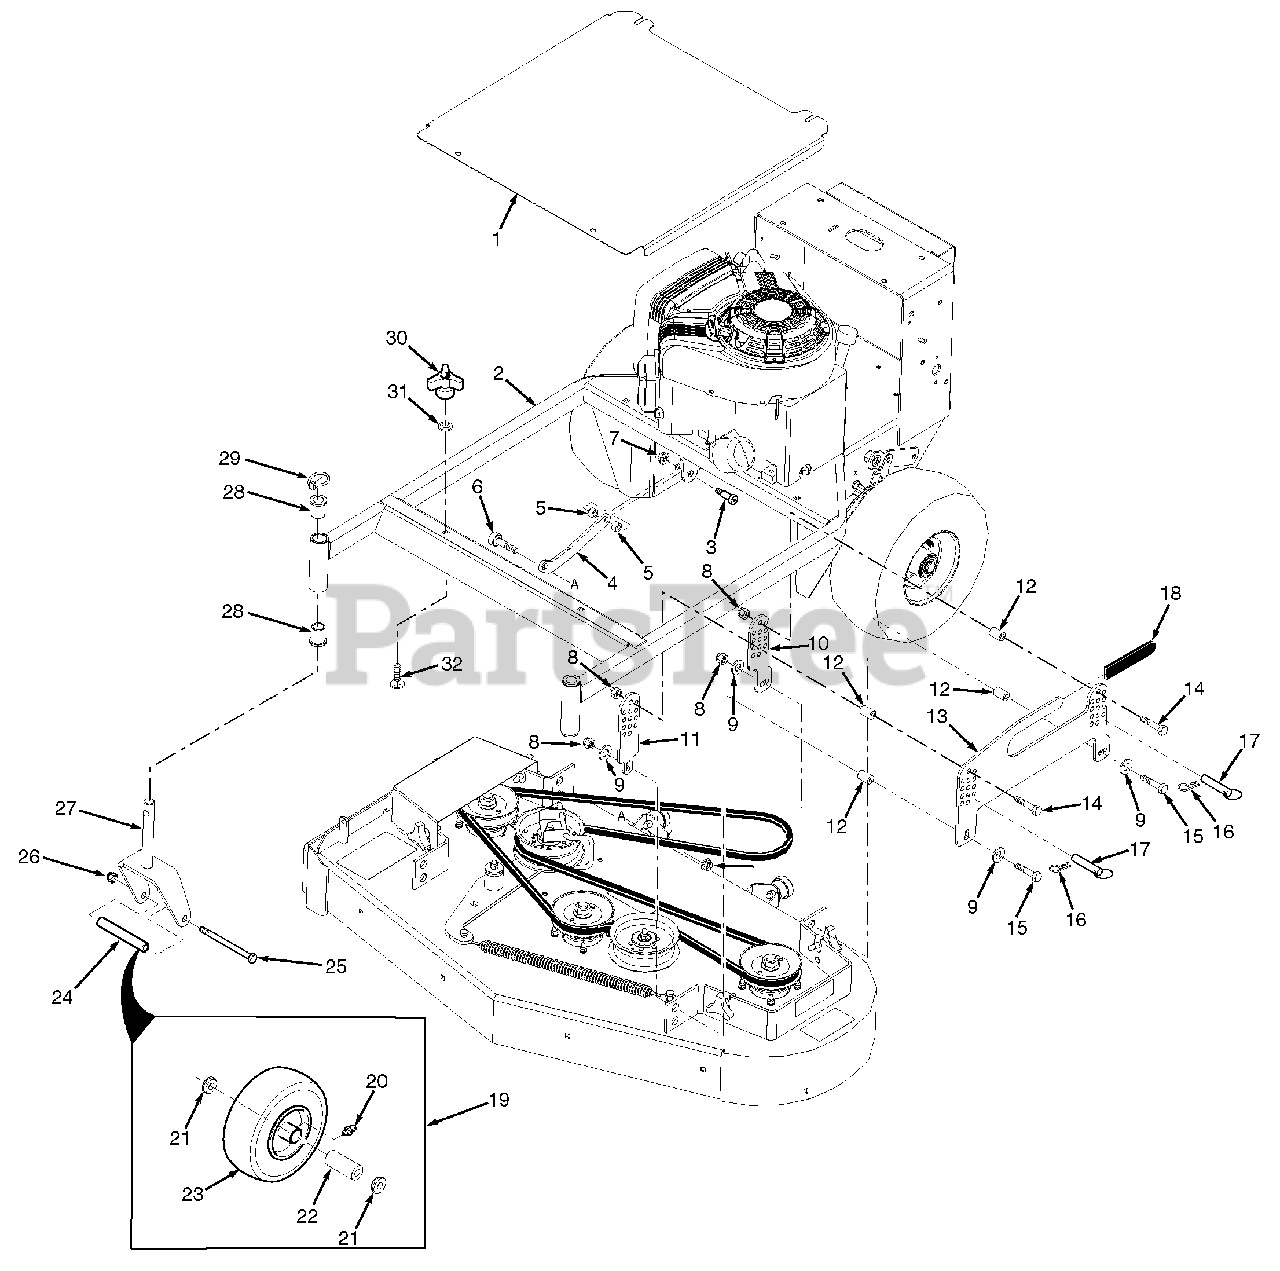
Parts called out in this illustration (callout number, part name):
1	Belt Cover, SFW w/Decals
2	Frame Weldment w/Decals
3	Bolt, Shoulder 1/2 x 1-1/2"
4	Pusharm
5	Spacer
6	Bolt, Shoulder 1/2 x 2-3/4"
7	Nut, Serrated Flange 3/8-16
8	Nut, Elastic Stop 3/8-16
9	Flatwasher, 3/8-.391 x .938 x .105 HD
10	Mounting Bracket, Height Adjustment Rear
11	Mounting Bracket, Height Adjustment Front
12	Spacer
13	Bracket, Deck Lift Height Adjustment - LH w/Decal
14	Bolt, Hex Head 3/8-16 x 2-1/4"
15	Bolt, Hex Head 3/8-16 x 2-1/2"
16	Hair Pin Cotter, .094 x 1.62"
17	Pin, Ring 3/8 x 2-1/2"
19	Caster Wheel Assembly, 9 x 3.5-4
20	Grease Fitting, 45 Degree 1/4-28
21	Bearing, Oilite
22	Bearing, Roller
23	Tire Only, Caster Wheel
24	Sleeve, Caster Wheel
25	Bolt, Hex Head 1/2-13 x 5-1/2"
26	Nut, Elastic Stop 1/2-13
27	Caster Yoke Weldment
28	Bearing
29	Quick Pin
30	Wing Nut, 3/8" Plastic Small
31	Nut, Push-On 3/8"
32	Bolt, Carriage 3/8-16 x 1"
